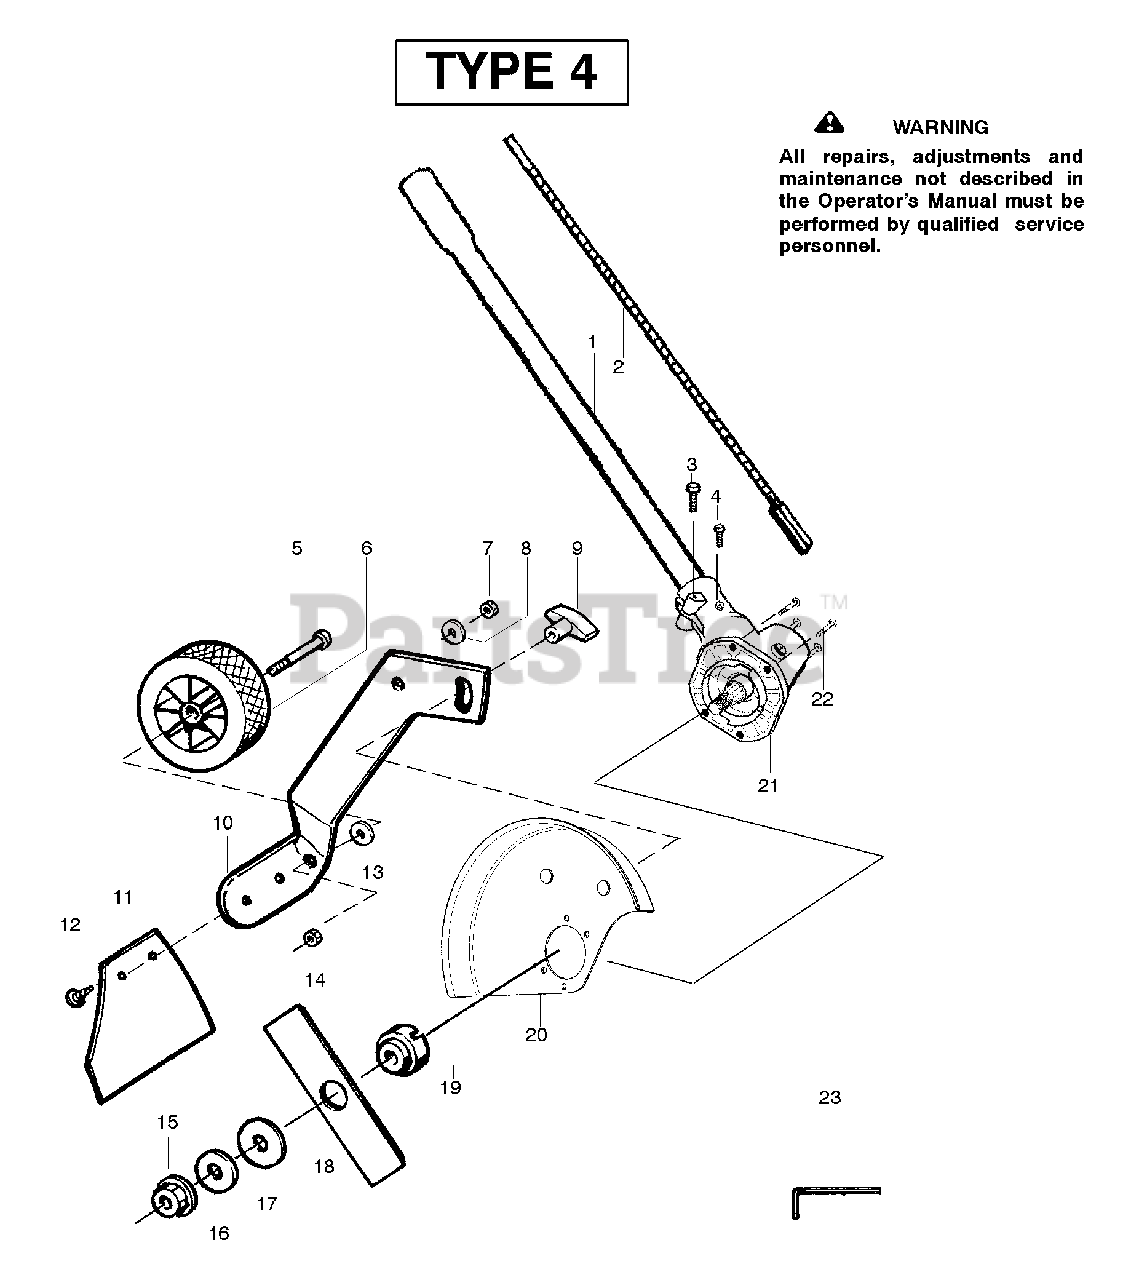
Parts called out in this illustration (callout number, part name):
1	Assy.-Driveshaft
2	Flexshaft-Split boom
4	Screw-Alignment
5	Bolt-Shoulder Axle
6	Wheel-4"
10	Bracket-Adj. Wheel
11	Kit-Mud Flap
12	Fastener-Mud Flap
15	Nut-Flange
16	Washer-Belleville
17	Washer-Flat
18	Accy-7.5" Blade
20	Kit-Edger Guard
21	Kit-Gearbox
23	Wrench-Hex (5/32")
